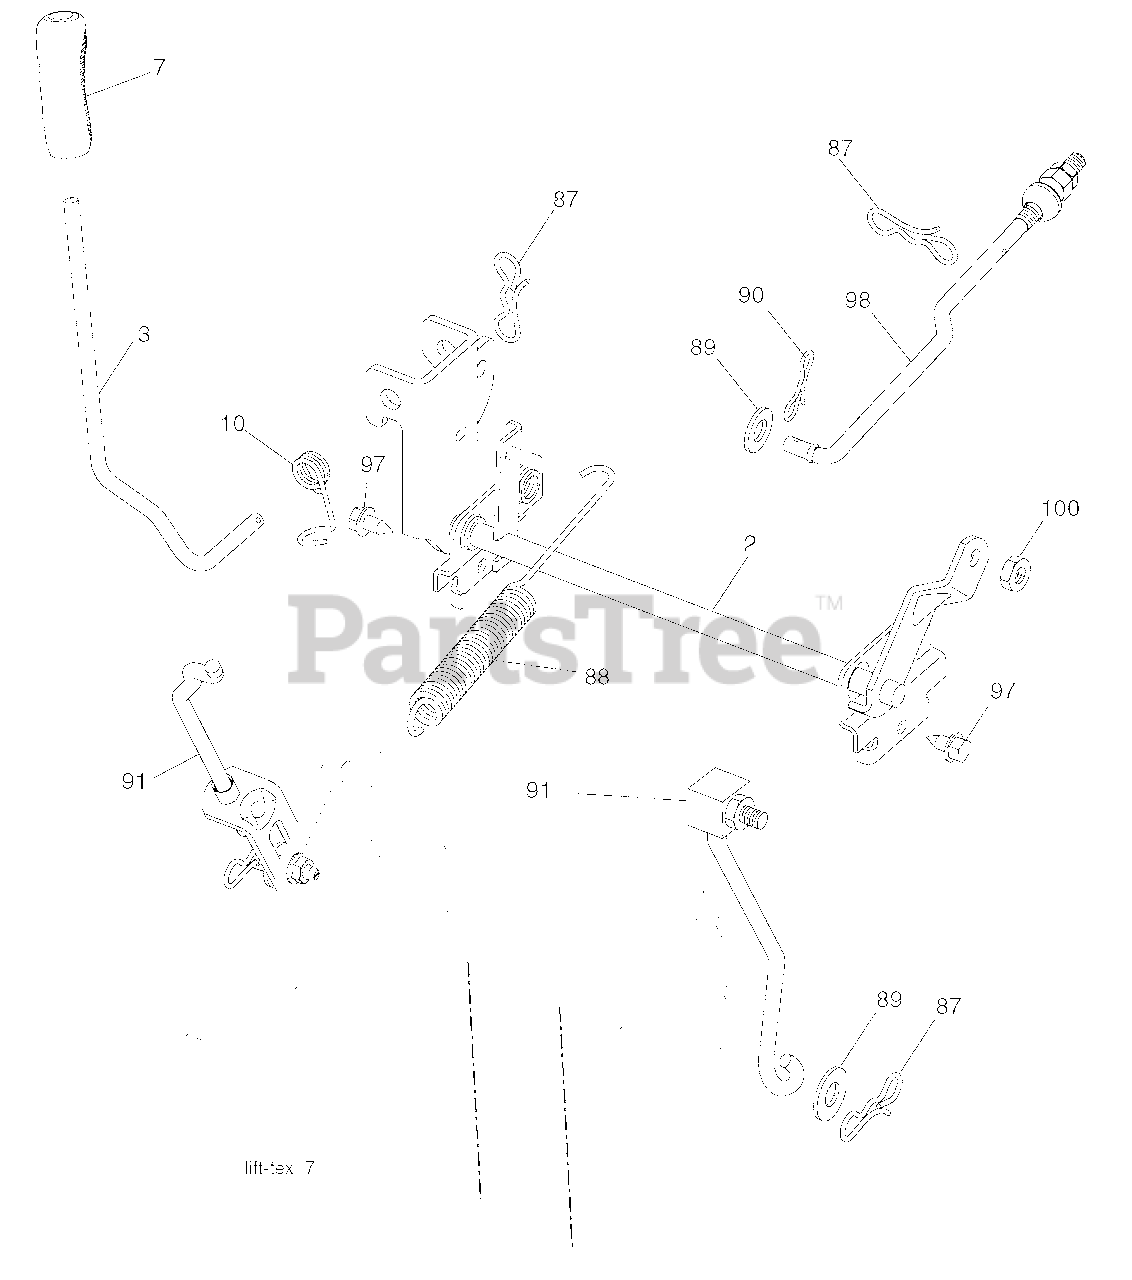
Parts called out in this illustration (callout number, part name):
2	Shaft Asm., Lift
3	Lever Asm., Lift RH
7	Grip, Lever
10	Spring Torsion
87	Pin Cotter 7/16 Bow Tie Lock
88	Spring Lift Assist
89	Washer Clear Zinc
90	Pin Cotter 5/16 Bow Tie Lock
91	Link Asm. Lift Rear
97	Screw 3/8-16 x .75 Smgml Tap/R.Z
98	Link Lift Susp. Front Mower
100	Nut Centerlock 3/8-16 unc
